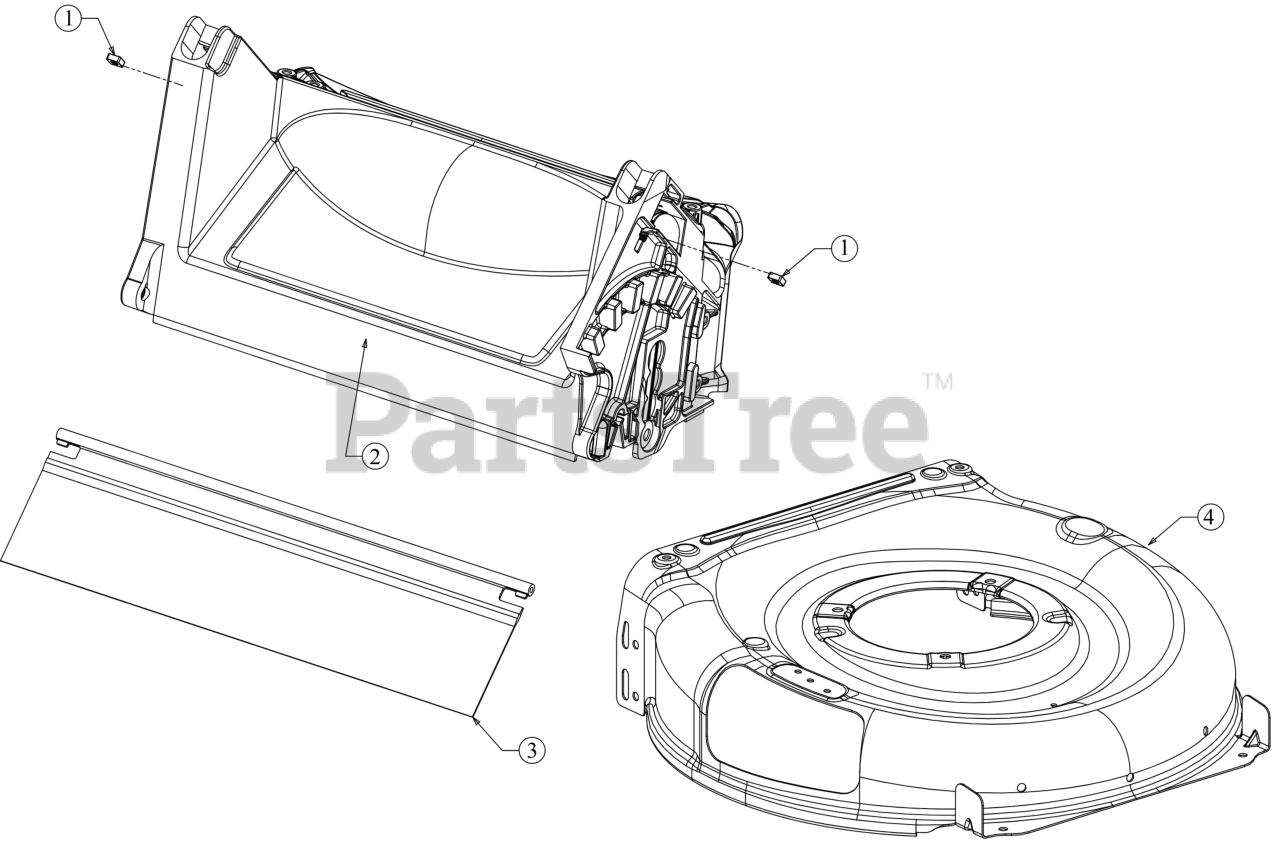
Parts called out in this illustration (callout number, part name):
1	SQUARE NUT 1/4-20
2	REAR BAFFLE ASSEMBLY
3	TRAILSHIELD
